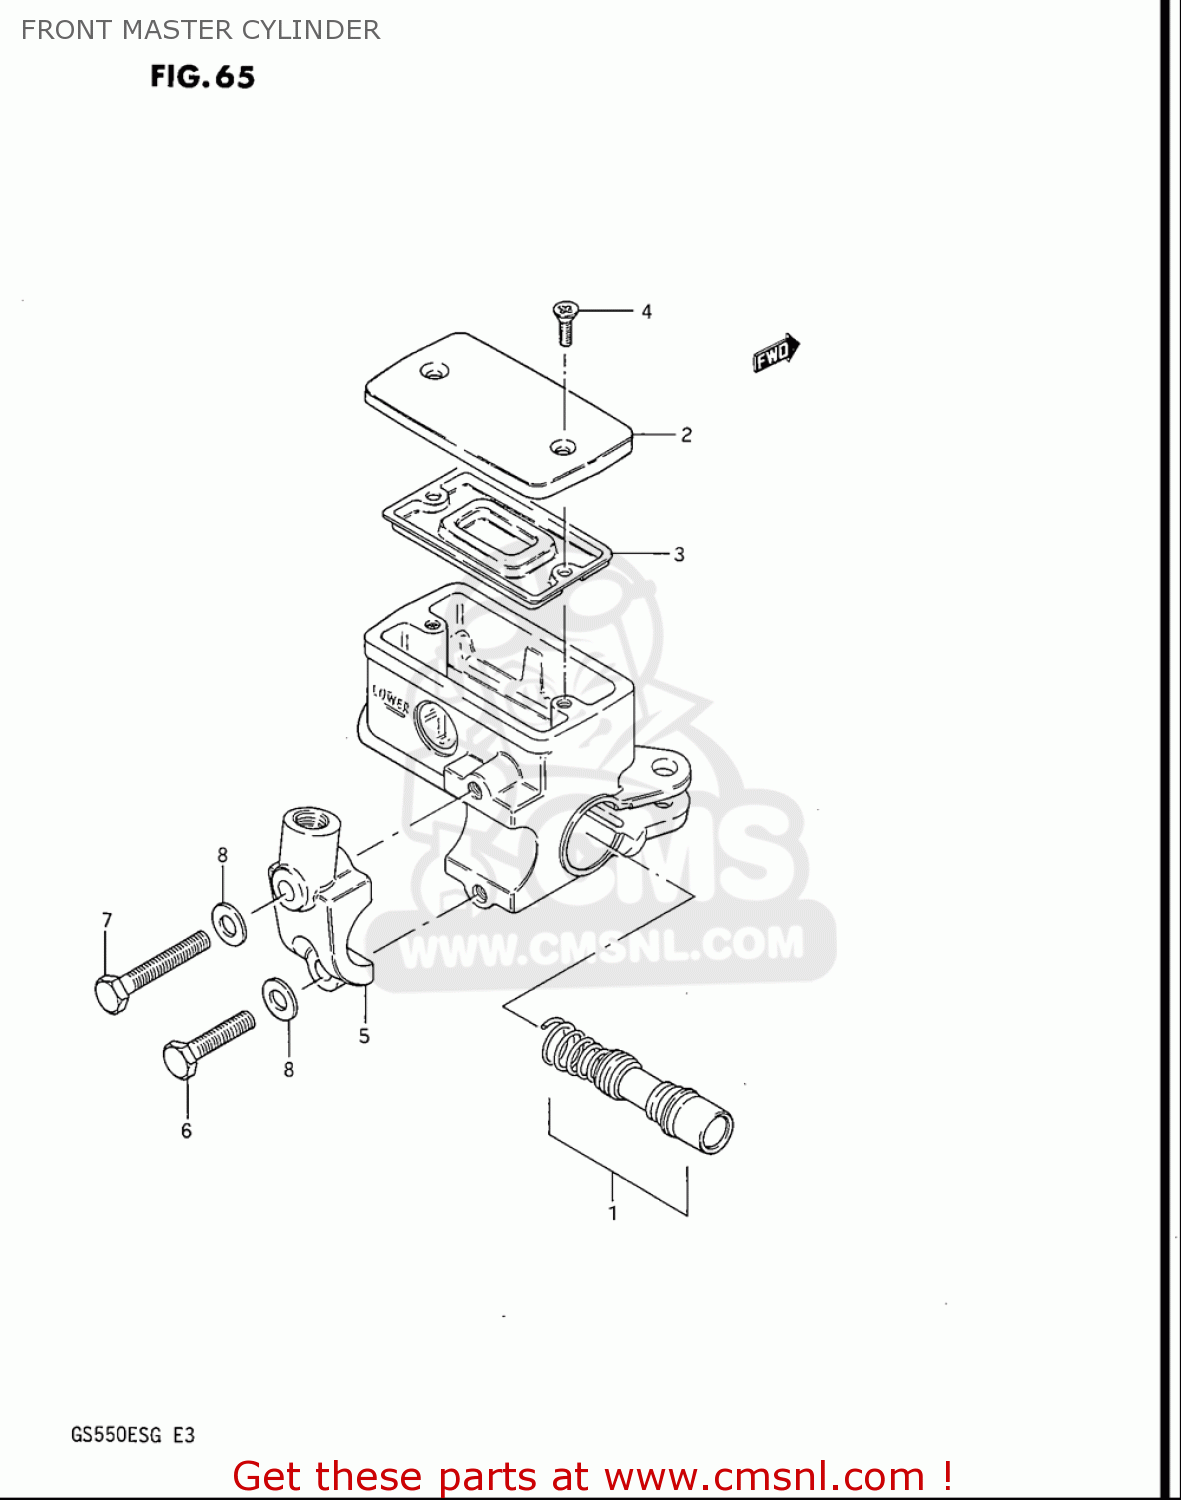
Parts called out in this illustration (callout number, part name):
1	PISTON & CUP SET
2	CAP
3	4
4	SCREW
5	HOLDER
6	BOLT
7	BOLT
8	WASHER
